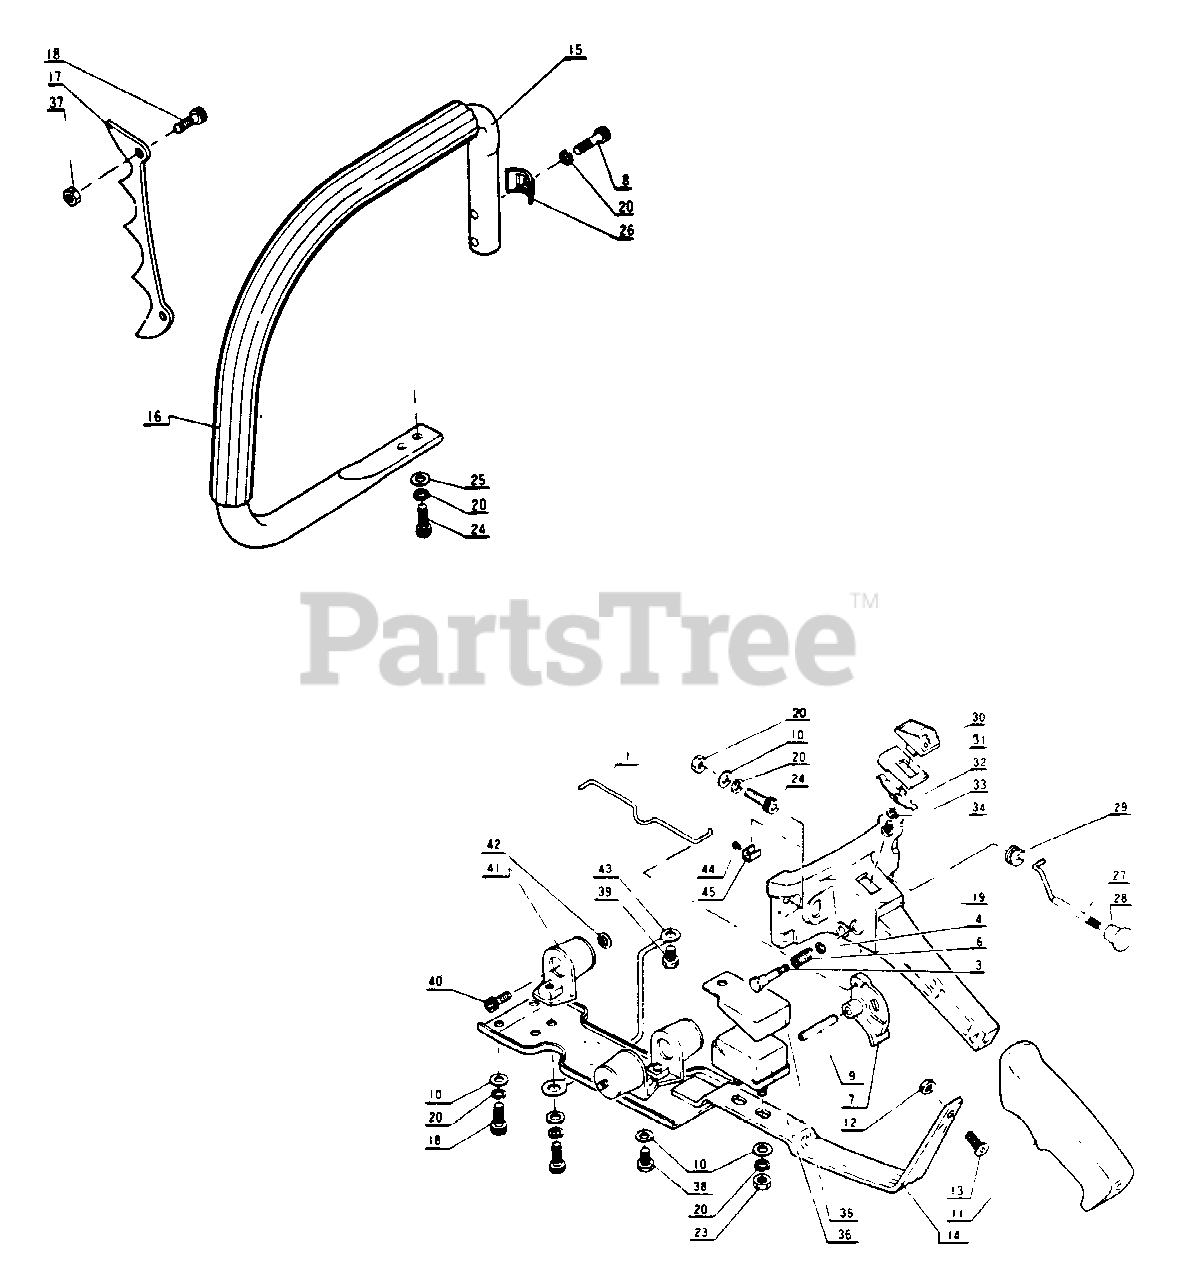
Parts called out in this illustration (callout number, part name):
1	ROD, CHOKE
3	LOCKOUT, TRIGGER
4	E-RING 3
6	LEAF SPRING
7	TRIGGER, THROTTLE
8	BOLT
10	WASHER 6.5×11.5×0.8
11	RIGHT HANDLE RUBBER
12	NUT, LOCK
13	SCREW - 6×10
14	RIGHT HANDLE SUPPORTER
15	LEFT HANDLE
16	GRIP, HANDLE
17	BUMPER, SPIKED
18	BOLT
19	RIGHT HANDLE
20	WASHER, SPRING 6
23	NUT, LOCK
24	BOLT
25	WASHER
26	HANDLE SET PLATE
27	ROD, CHOKE
29	GROMMET, RUBBER
30	IGNITION SWITCH ASSY
31	GUIDE, SWITCH
32	CONTACT, SWITCH
33	WASHER, SPRING 4 MM
34	SCREW - 4×8
35	STOPPER B
36	STOPPER A
37	NUT, HEX M6
39	BOLT 6×10
40	BOLT
41	CUSHION
42	WASHER, SEAL
43	LEAD - GROUND
44	PLATE - GROUND
45	RIVET
